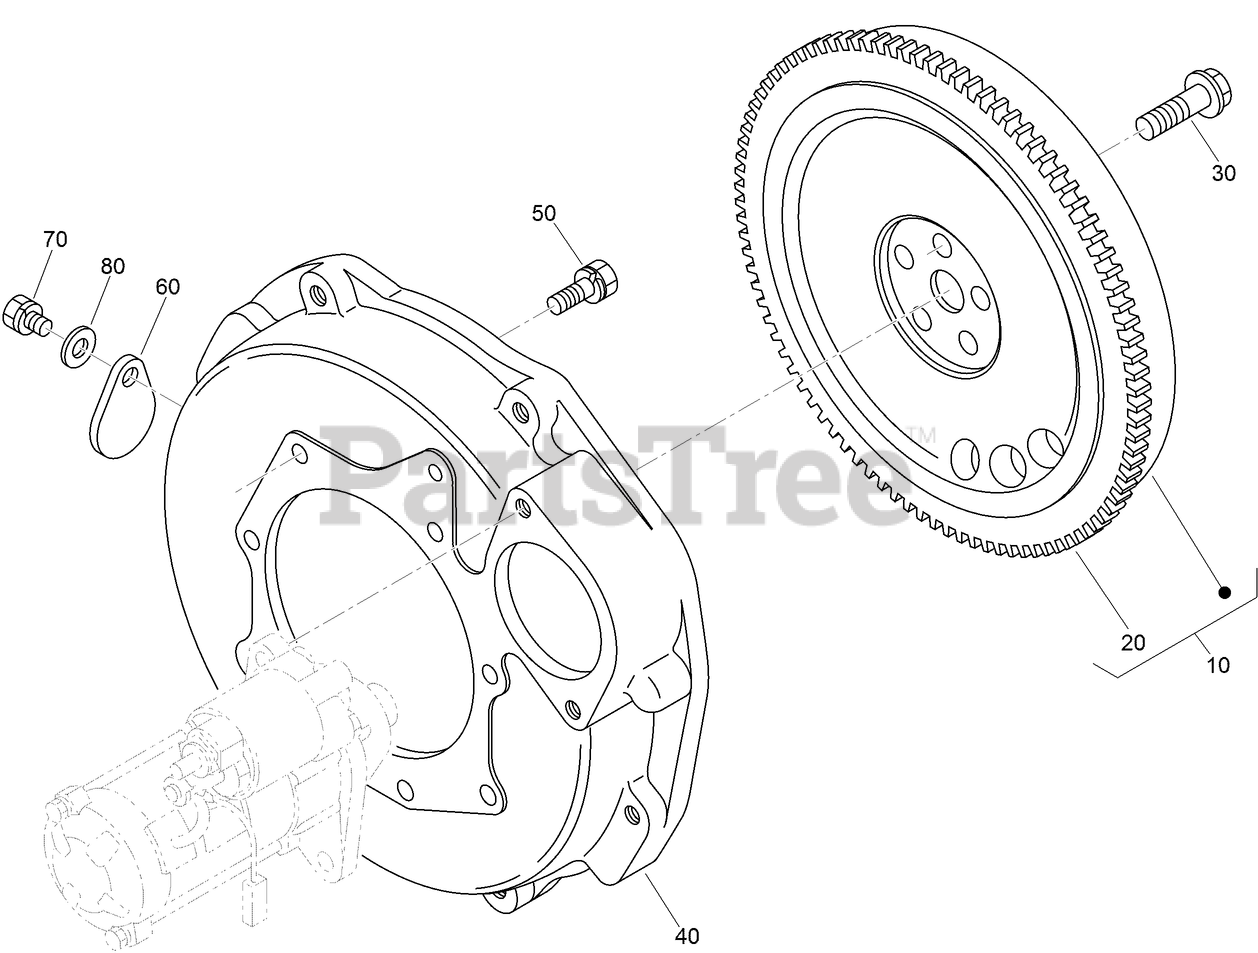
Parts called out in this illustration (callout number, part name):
10	FLYWHEEL ASM
20	GEAR-RING
30	BOLT-FLYWHEEL
40	HOUSING-FLYWHEEL
80	WASHER-PLAIN
